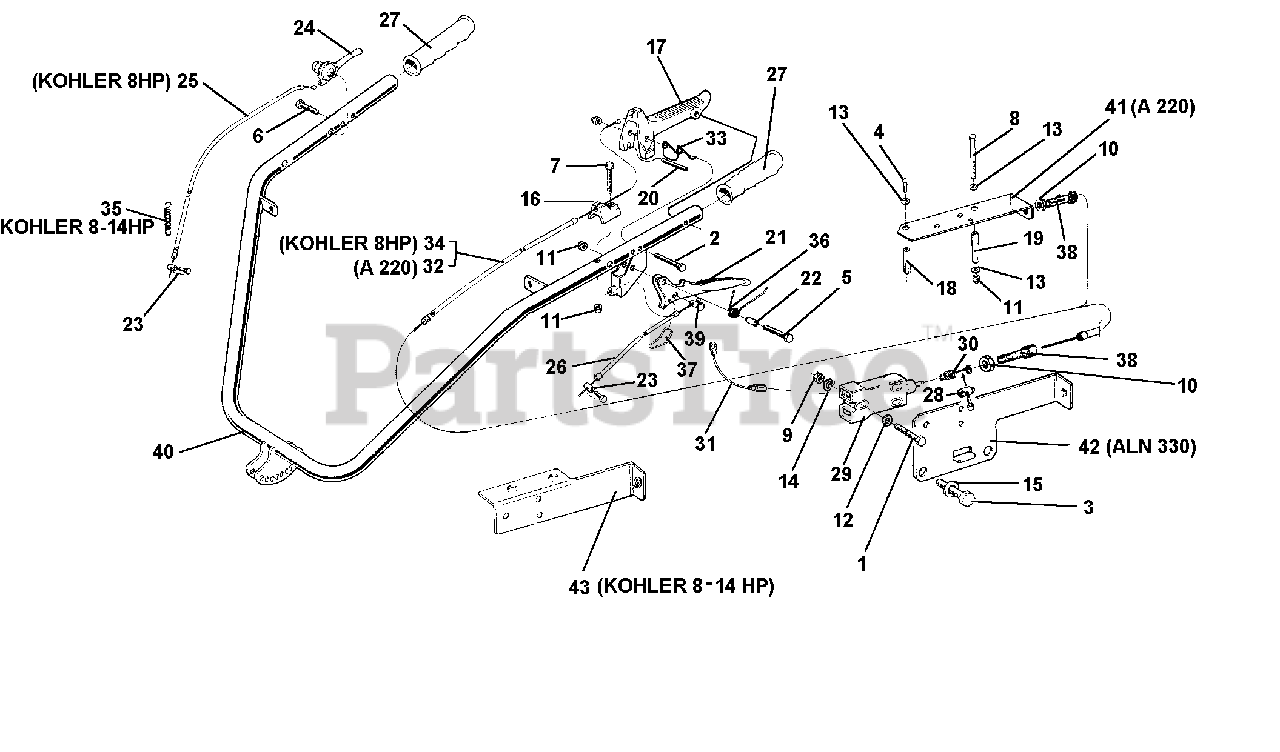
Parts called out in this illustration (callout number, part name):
1	SCREW TE M4 X 25
2	SCREW TE M6 X 45
3	SCREW TE M8 X 12
4	SCREW M6 X 12
5	SCREW M6 X 25
6	SCREW M6 X 40
7	SCREW M6 X 35
11	NUT, SELF LOCKING M6
12	FLAT WASHER 4.3
13	WASHER, LOCK 6.4
14	LOCK WASHER B 4.3
15	WASHER, LOCK 8.4
16	SHEATH STOP OF MOTOR STOP
17	MOTOR STOP LEVER
19	PROTECTION SPACER
20	LEVER STOP FOR MOTOR STOP
21	CLUTCH LEVER
22	LEVER SPACER
23	CLAMP, CABLE
24	LEVER, ACCELERATOR
25	GAS WIRE AND SHEATH
26	CABLE & SHEATH, CLUTCH
28	CABLE CLAMP
29	STOP SWITCH
30	SWITCH SPRING
31	SWITCH CABLES
32	SHEATH CABLE
33	MOTOR STOP LEVER SPRING
34	SHEATH CABLE
35	KOHLER GAS CONTROL
36	LEVER SPRING
38	ADJUSTING SCREW
41	SWITCH SUPPORT
42	SUPPORT FOR ACME STOP SWITCH
43	KOHLER STOP SWITCH SUPPORT
